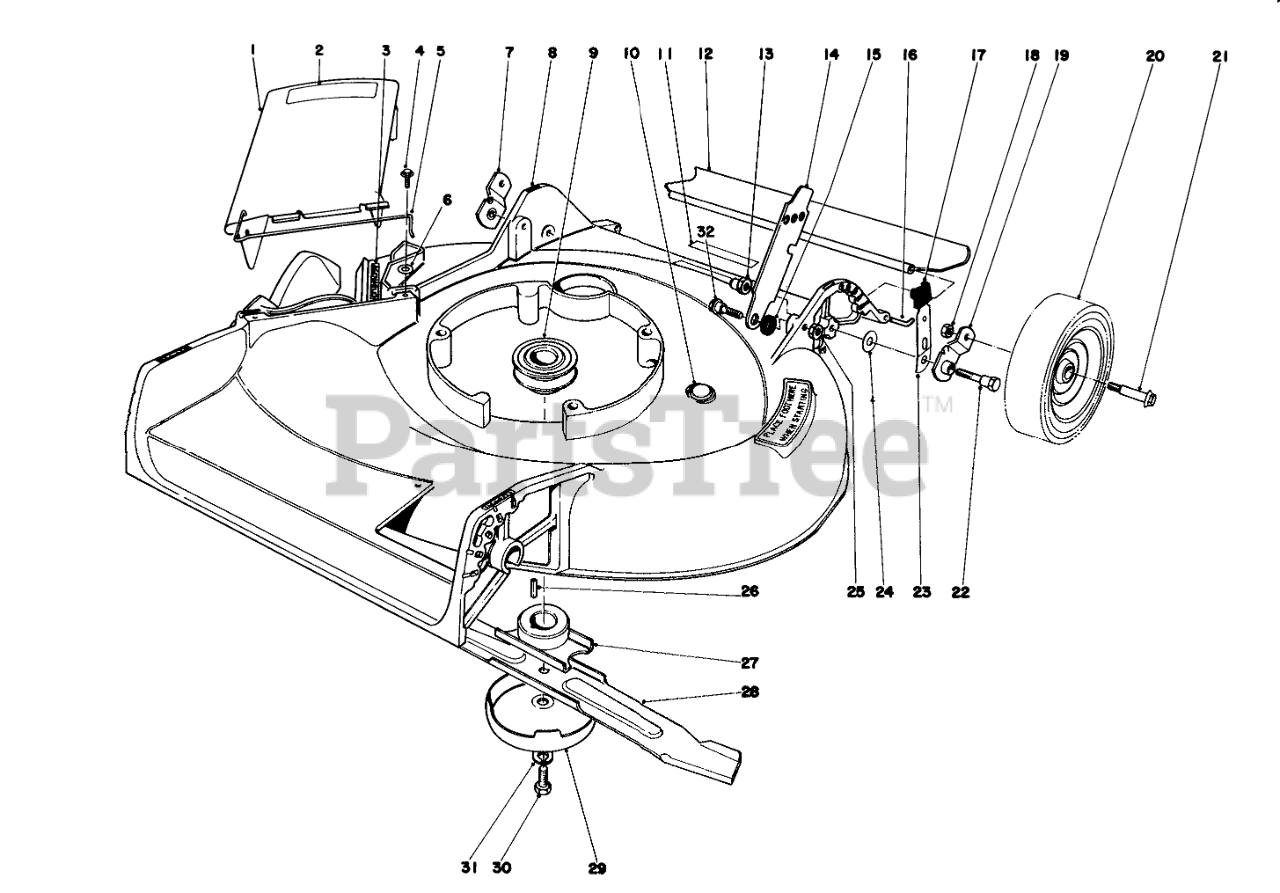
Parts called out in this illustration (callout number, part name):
1	Deflector Cover Assembly (Incl. Ref. #2 & 5)
2	Decal-Caution (French & Dutch)
3	Decal-Danger (French & Dutch)
4	SCREW
5	SPRING HINGE
6	WASHER-FLAT
7	Pivot Arm
8	Housing
9	DRIVER PULLEY
11	Decal-Noise (French)
12	Rear Shield
13	HANDLE PIVOT NUT
14	Latch
15	HANDLE LATCH SPACER
16	SHIELD ROD
17	KNOB-ARM
18	Nut
19	Pivot Arm
20	Wheel Assembly
22	5/16-18 PIVOT SCREW
23	SPRING ARM ASM
24	WASHER-PIVOT
25	Nut
26	KEY-SQUARE
27	Blade Retailer
28	Blade
29	AntiScalp Cup
30	SPECIAL SCREW
31	WASHER-LOCK
32	SCREW-SHOULDER
